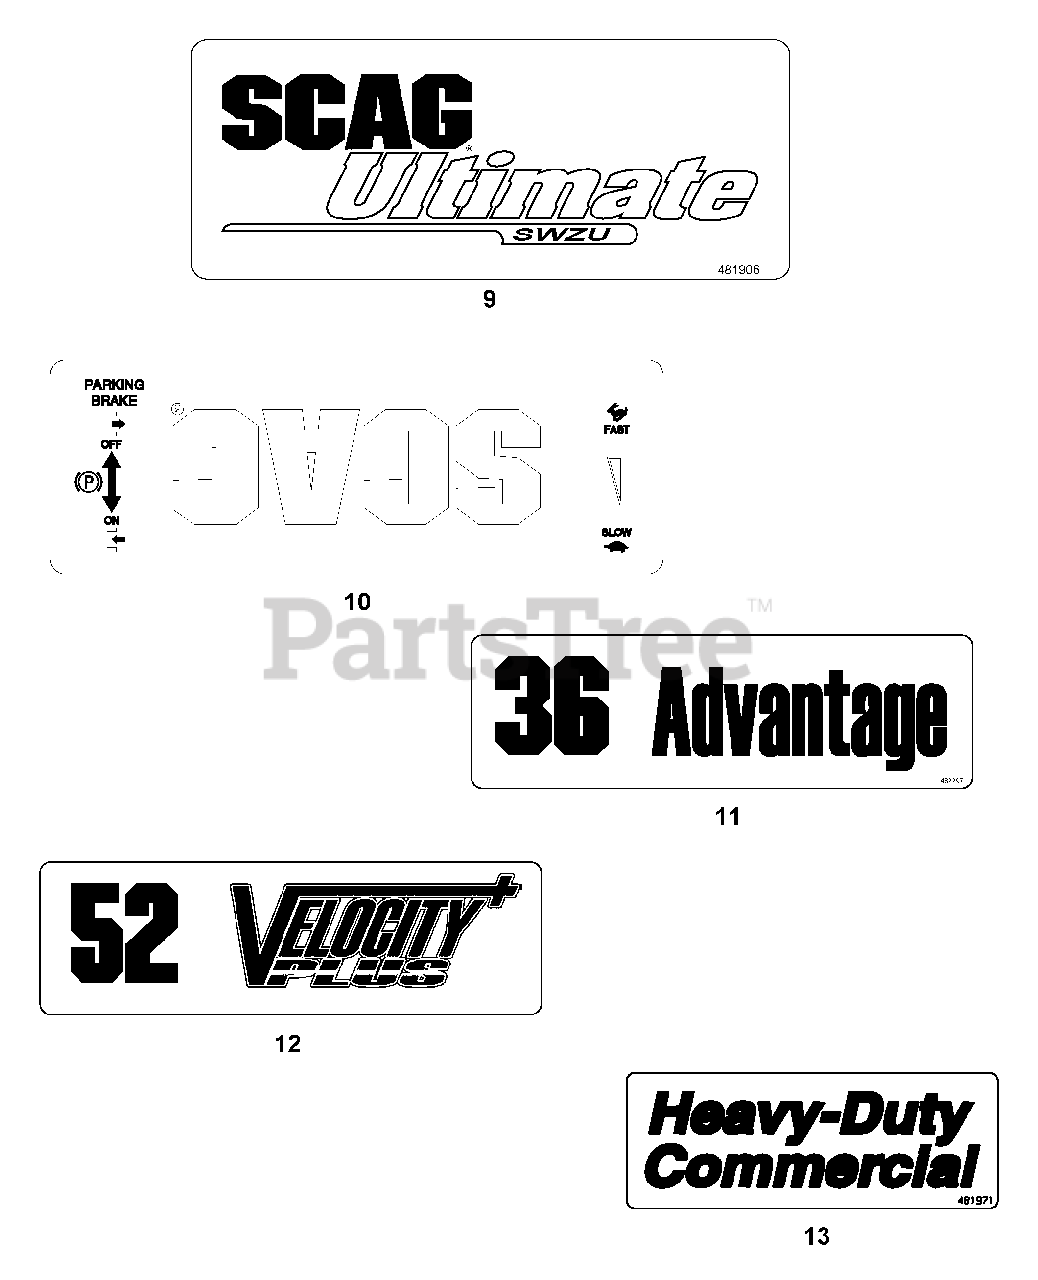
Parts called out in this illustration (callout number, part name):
9	Decal, SWZU - Ultimate
10	Decal, Instrument Panel - Front
11	Decal, 36 Advantage
12	Decal, 48 Velocity Plus
13	Decal, Heavy Duty Commercial
